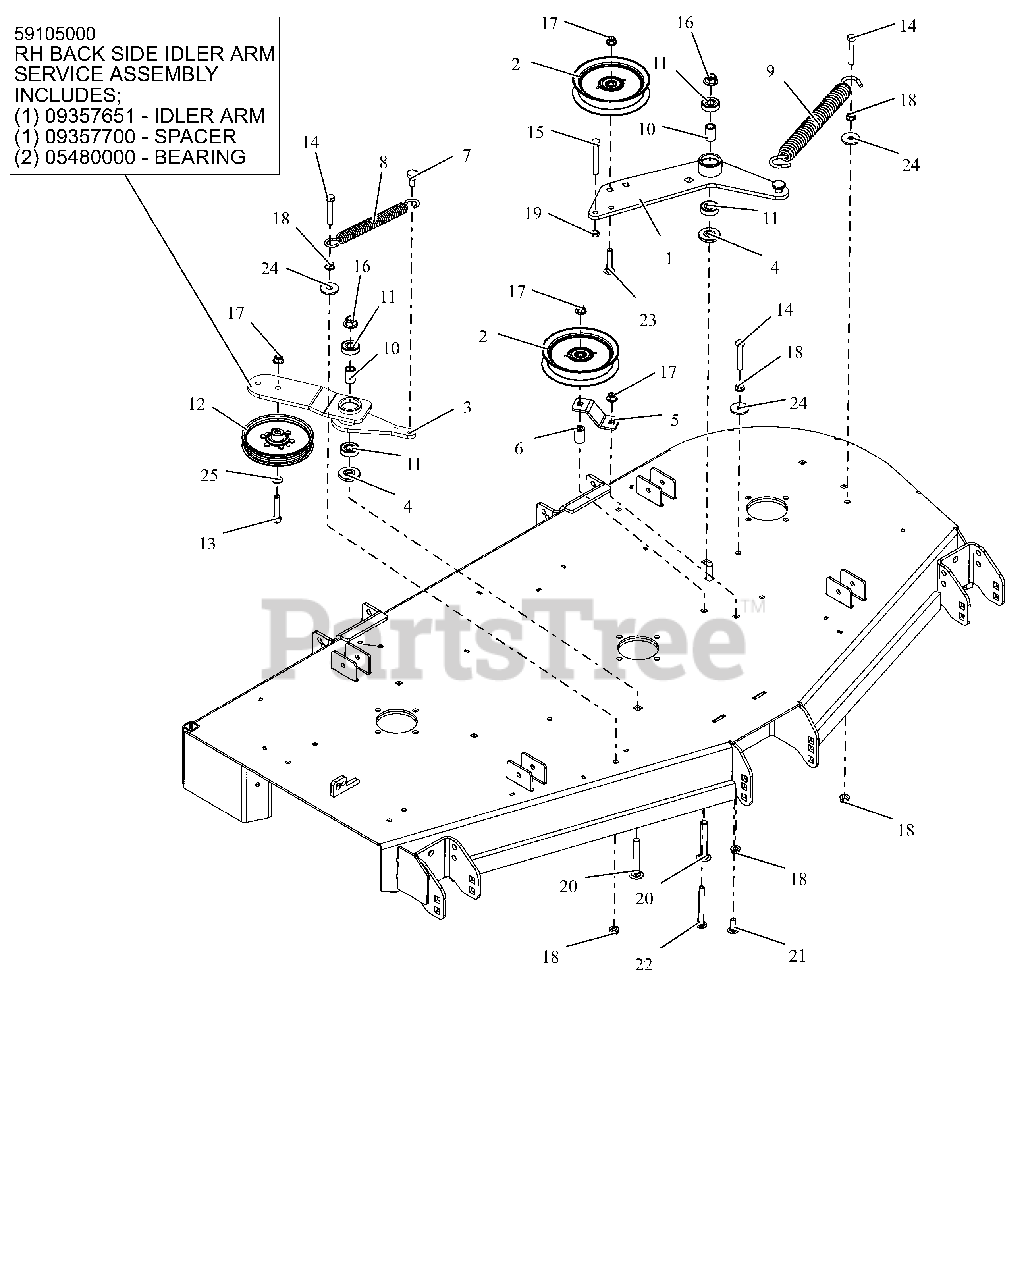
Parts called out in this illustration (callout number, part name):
1	DECK PTO IDLER ARM WLDMT - BLK
2	IDLER, FLAT 5.00"
3	DECK RH IDLER ARM WMT - BLK
3	RH BACKSIDE IDLER ARM ASSEMBLY
4	SPACER, IDLER ARM
5	PTO FIXED IDLER MTG BRKT -RED
6	BUSHING, SLV .380X.750X1.190
7	BLT,SHLDR EP .38-16X.30 HEX YZ
8	SPRING, EXTENSION
9	SPRING, EXTENSION
10	SPACER .510 X .75 X 1.1485
11	BRG-BALL .500X1.38X.437
12	PULLEY, FLAT IDLER
13	BLT,HEX .38-16X2.00 G5 ZCC
14	BLT,HEX .38-16X2.25 G5 ZCC
15	BLT, HEX .38-16X2.75 G5 ZCC
16	NUT,NYL-FLG .50-13 GF ZCC
17	NUT,NYL-FLG .38-16 GF ZCC
18	NUT, SPNLK-FLG .38-16 G5 ZCC
19	NUT-JAM .375-16 G2 ZCC
20	BTL,RHSSN .500-13 X 3.25 G5 ZCC
21	BLT,RHSSN .38-16X1.00 G5 ZCC
22	BLT,RHSSN .38-16X3.50 G5 ZCC
23	BLT,RHSSN.375-16X2.00 G5 ZCC
24	WSHR,FLT .406X1.375X.135 ZCC
25	WSHR,FLT .406X.812X.065 ZCC
